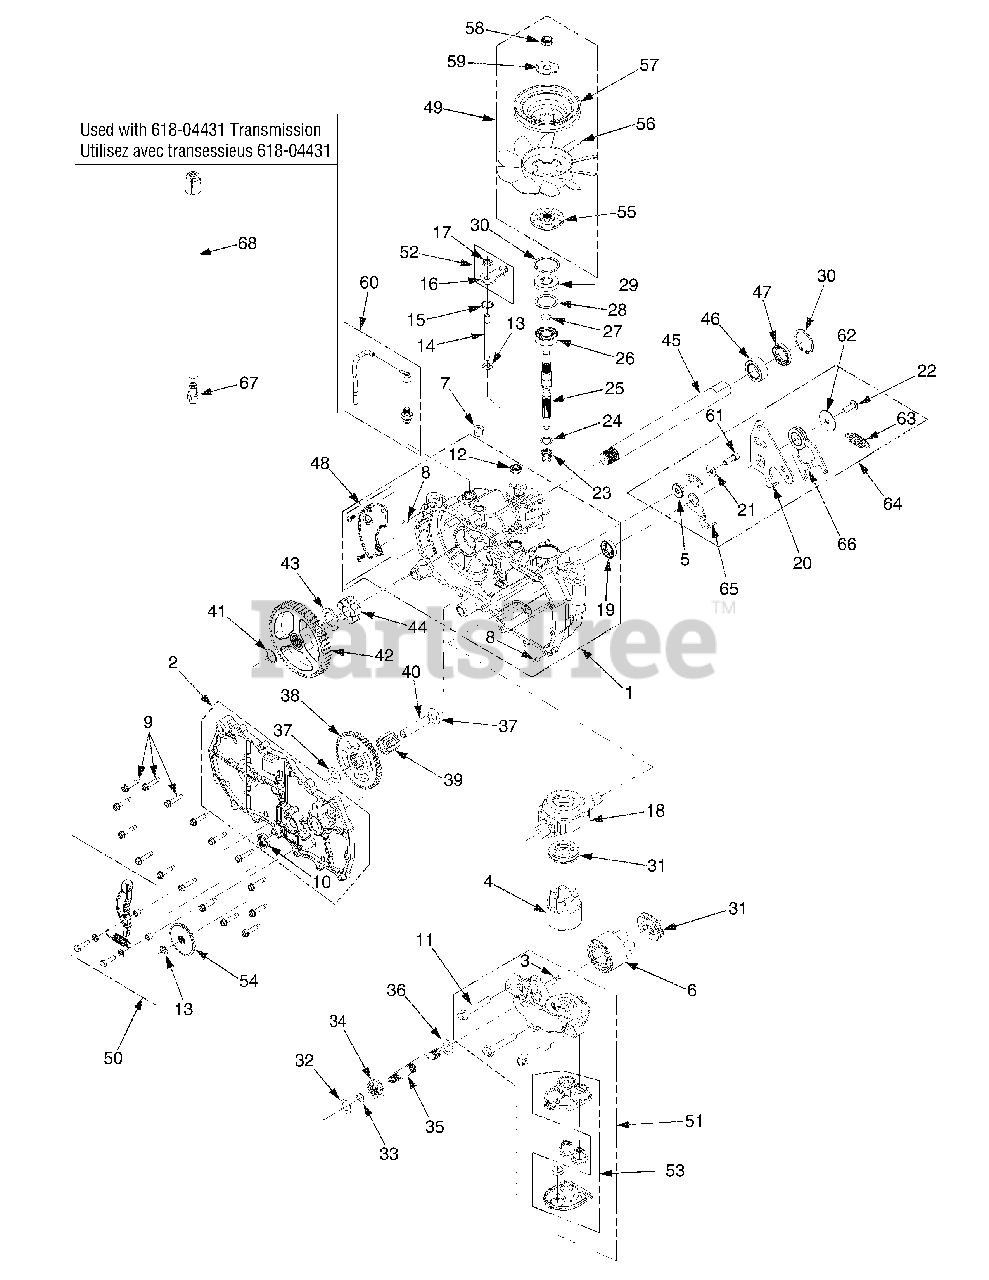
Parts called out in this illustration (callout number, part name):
1	Housing Ass’y, Main LH
2	Side Assembly LH
3	Plate, Bypass
4	Block Kit - 7 Piston
5	Spacer, .32 x 1.005 x .179
6	Block Assembly, Cylinder
7	Straight Thread Pipe
8	Std. Handle Pin
9	Hex Flange Screw
10	Oil Seal .625 x 1.0 x .25
11	Screw
12	Seal, Lip
13	Retaing Ring .375 Ext.
14	Rod, Bypass
15	Retaining Ring .75 Int.
16	Arm, Bypass
17	Retaining Ring
18	Swashplate, trunnion
19	Seal, Lip
20	Control Arm LH
21	Washer 7/16 x 7/8 x .060
22	Screw, 5/16-24 x 1.0
23	Block Washer
24	Block Thrust Washer
25	Input Shaft
26	Ball Bearing
27	Retaining Ring
28	Spacer
29	Lip Seal
30	Retaining Ring
31	Thrust Washer
32	Flat Washer 5/8 x 1.0 x .05
33	Retaining Ring
34	Gear, Pinion, 13T
35	Shaft, Motor
36	Motor Shaft Washer
37	Washer, HT
38	Gear, 10T/48T
39	Gear, 10T Jackshaft
40	Pin, Jackshaft
41	Retaining Ring
42	Gear, Bull, 52T
43	Washer, 1.018 x 1.57 x .105
44	Sleeve Bearing
45	Shaft, Axle, 1.0 x 11.7
46	Bearing, Sleeve
47	Seal, Lip
48	Plate Kit, Expansion
49	Kit, Fan Pulley
50	Kit, Brake Arm
51	Kit, Center section
52	Kit, Bypass Arm RH
53	Filter Assembly
54	Disc, Brake Cog
55	Hub, Pulley
56	Fan, 7" 10 Blade
57	Pulley, 4.5
58	Hex Ins. L-Nut 1/2-20
59	OD Slotted Washer
60	Breather Kit
61	Screw, Patch 5/16-24 x 1
62	Washer, .343 x 1.5 x .062
63	Extension Spring
64	Kit, Return Ass’y LH
65	Neutral Arm RH
66	Scissors Arm Kit
67	Fit ting w/cap
68	Hose Assembly, breather
68	Seal Kit
68	Sealant
